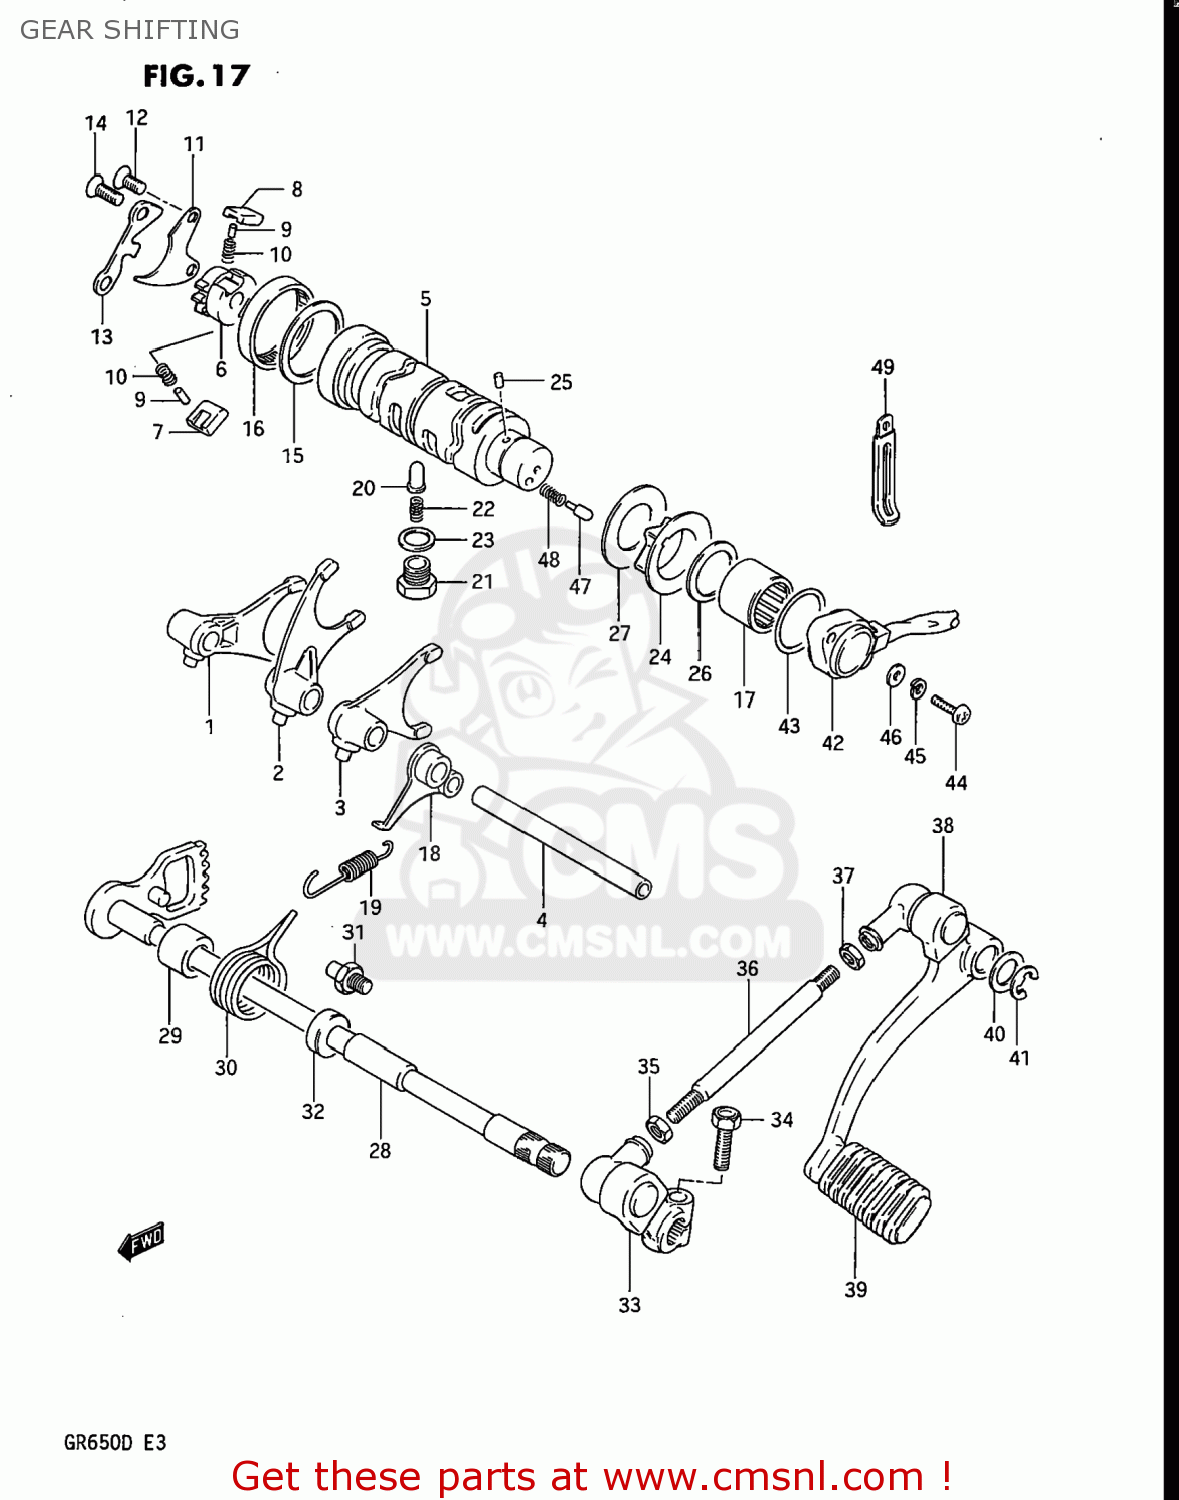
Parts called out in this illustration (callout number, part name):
1	FORK,GEAR SHIFT NO.1
2	FORK,GEAR SHIFT NO.2
3	FORK,GEAR SHIFT NO.3
4	SHAFT,GEAR SHIFT FORK
5	CAM,GEAR SHIFT
6	RETAINER,GEAR SHIFT CAM
7	PAWL,GEAR SHIFT NO.1
8	PAWL,GEAR SHIFT NO.2
9	PIN(5X8)
10	SPRING
11	LIFTER,GEAR SHIFT PAWL
12	SCREW
13	GUIDE,GEAR SHIFT CAM
14	SCREW
15	WASHER (40X49X1)
16	BEARING(43X49X12)
17	BEARING(25X32X12)
18	STOPPER,GEAR SHIFTING
19	SPRING
20	STOPPER,GEAR SHIFTING
21	HOLDER,GEAR SHIFT CAM STOP SPR
22	SPRING
23	GASKET(14X19.2X2) (NAS)
24	PLATE,GEAR SHIFT CAM STOPPER
25	PIN 4X6
26	WASHER
27	WASHER,LOCK
28	SHAFT,GEAR SHIFT
29	SPACER(12X20X15.3)
30	SPRING
31	STOPPER,GEAR SHIFT CAM
32	OIL SEAL
33	ARM,GEAR SHIFT
34	BOLT
35	NUT
36	ROD,GEAR SHIFT LINK
37	NUT
38	LEVER ASSEMBLY,GEAR SHIFTING
39	RUBBER,PEDAL
40	WASHER(12.5X20X1)
41	CIRCLIP
42	BASE ASSEMBLY,NEUTRAL SWITCH TERMINAL
43	O-RING (D:2.4 ID:26.2)
44	SCREW 5X20
45	LOCK WASHER
46	WASHER
47	PIN(5X15.5)
48	SPRING
49	CLAMP
